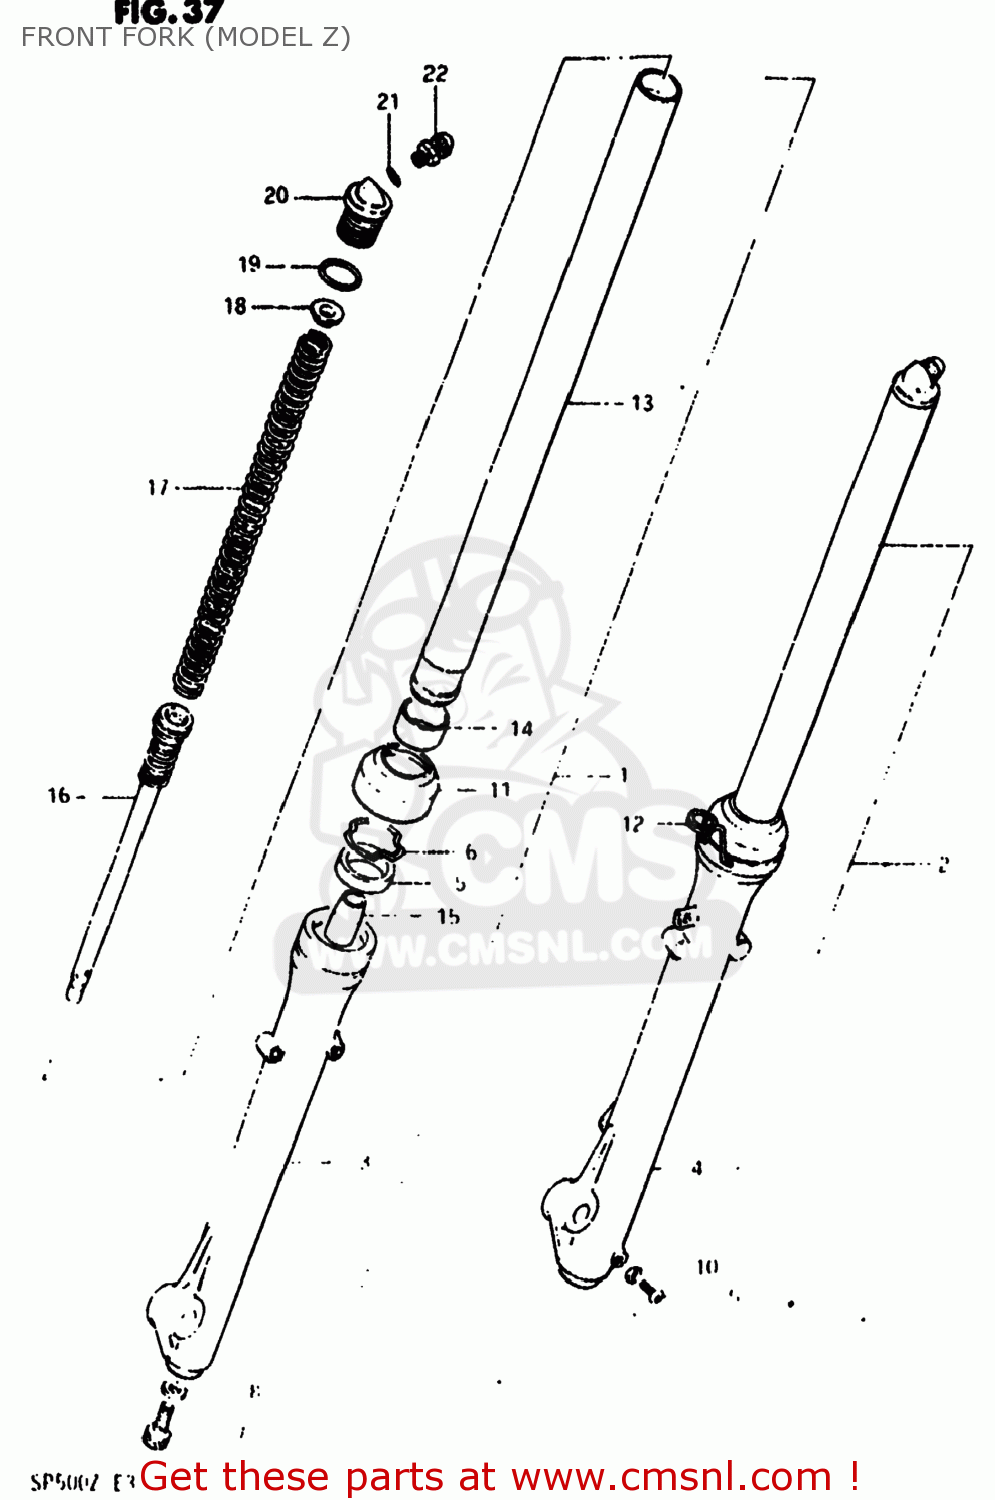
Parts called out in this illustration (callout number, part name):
1	DAMPER ASSEMBLY,RIGHT
2	DAMPER ASSEMBLY,LEFT
3	TUBE,OUTER,RIGHT
4	TUBE,OUTER,LEFT
5	OIL SEAL,FRONT FORK
6	7
7	BOLT,FORK CYLINDER(10X25)
8	GASKET (NAS)
9	SCREW
10	GASKET,DRAIN,PLUG (NAS)
11	SEAL,DUST
12	BAND,FRONT FORK COVER
13	TUBE,FORK,INNER
14	PISTON
15	PIECE,OIL LOCK
16	CYLINDER,FRONT FORK
17	SPRING,FRONT FORK
18	GUIDE,FRONT FORK SPRING C
19	O RING
20	BOLT,FORK
21	O-RING
22	VALVE,FRONT FORK AIR
